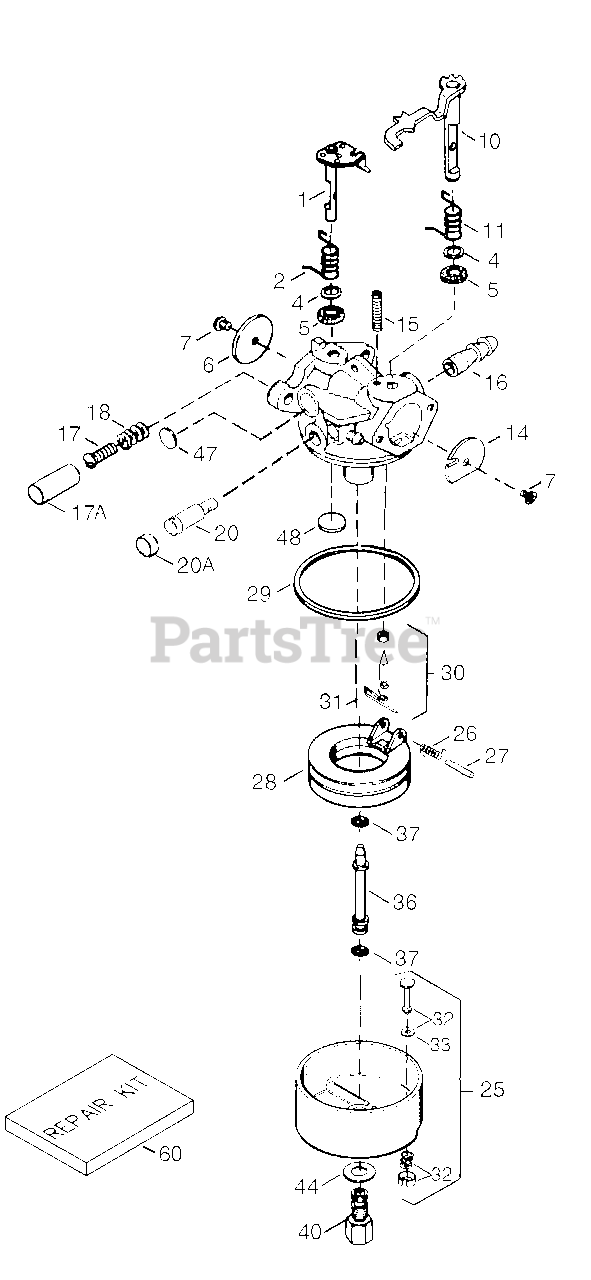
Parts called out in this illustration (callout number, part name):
1	Throttle Shaft & Lever Assembly
6	Throttle Shutter
7	* Shutter Screw
10	Choke Shaft & Lever Assembly
14	Choke Shutter
15	Choke Positioning Spring
16	Fuel Fitting
25	Float Bowl
26	Float Dampening Spring
27	* Float Shaft
28	Float
29	* Float Bowl "O" Ring
30	* Inlet Needle, Seat & Clip (Incl. 31)
31	Spring Clip
36	Main Nozzle Tube
37	* "O" Ring, Main Nozzle Tube
40	High Speed Bowl Nut
44	Bowl Nut Washer
48	* Welch Plug, Atmospheric Vent
60	Repair Kit Incl. items marked PK inn otes
